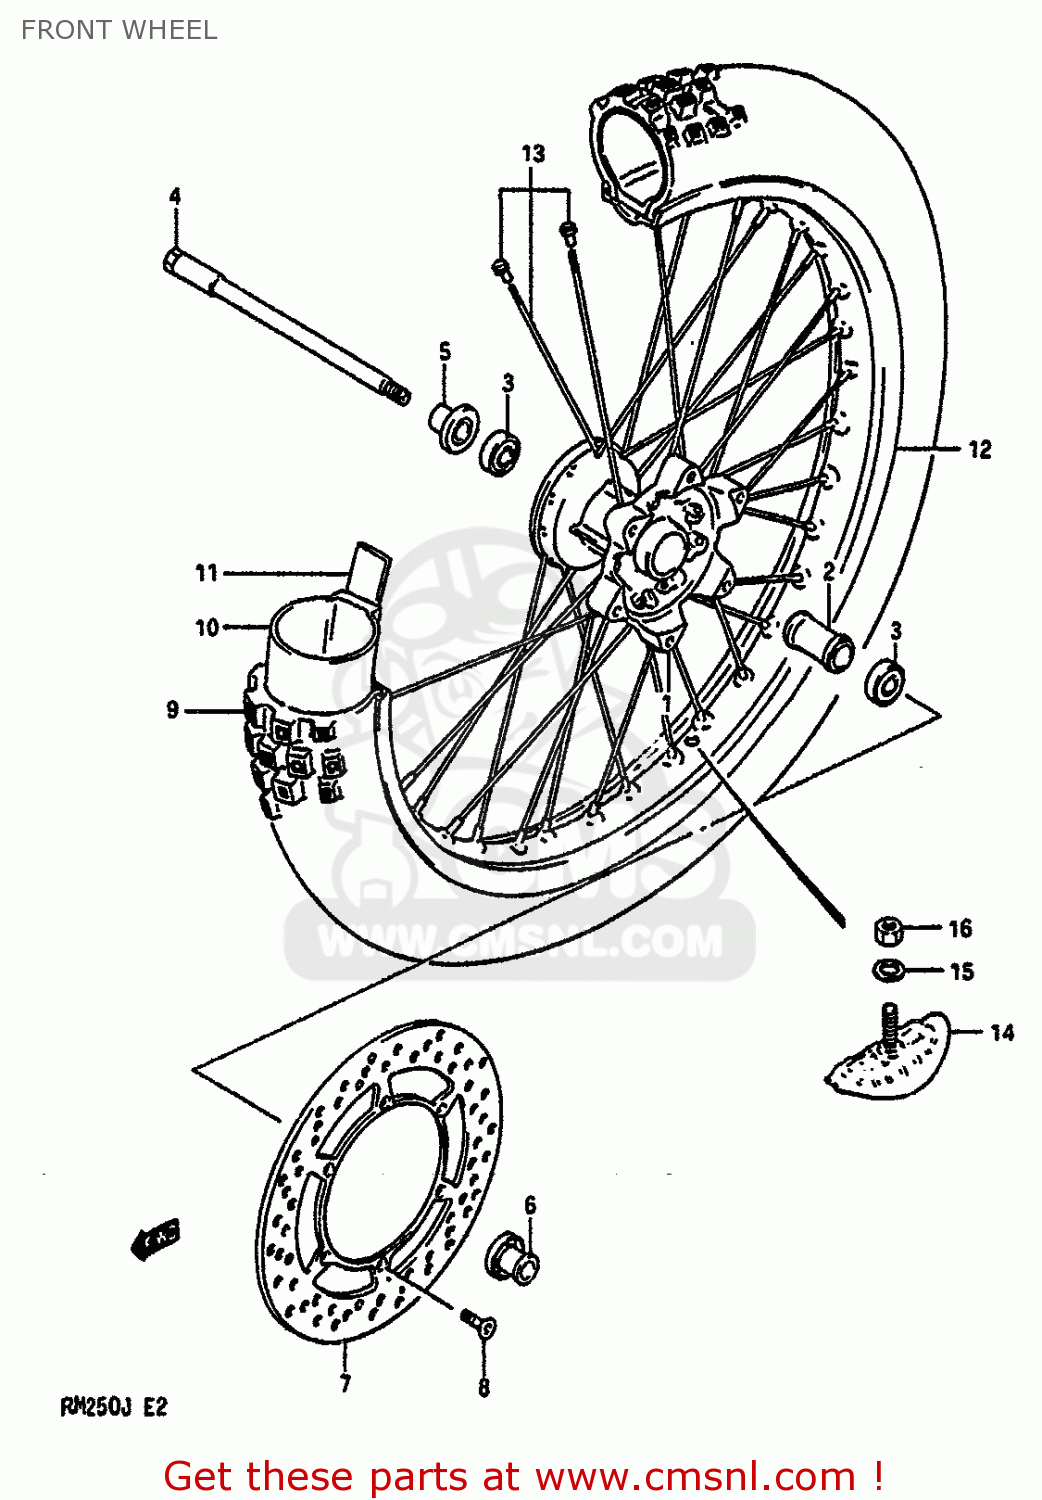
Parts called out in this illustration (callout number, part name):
1	HUB,FRONT
2	SPACER,FR HUB BEARING
3	BEARING
4	AXLE,FRONT
5	SPACER,FRONT AXLE,RIGHT
6	SPACER,FRONT AXLE,LEFT
7	DISC,FRONT BRAKE
8	SCREW
9	TIRE,FRONT 80/100-21
10	TUBE
11	PROTECTOR,WHEEL,INNER
12	RIM,FRONT WHEEL
13	SPOKE SET,FRONT
14	STOPPER,BEAD
15	WASHER
16	NUT 8MM
